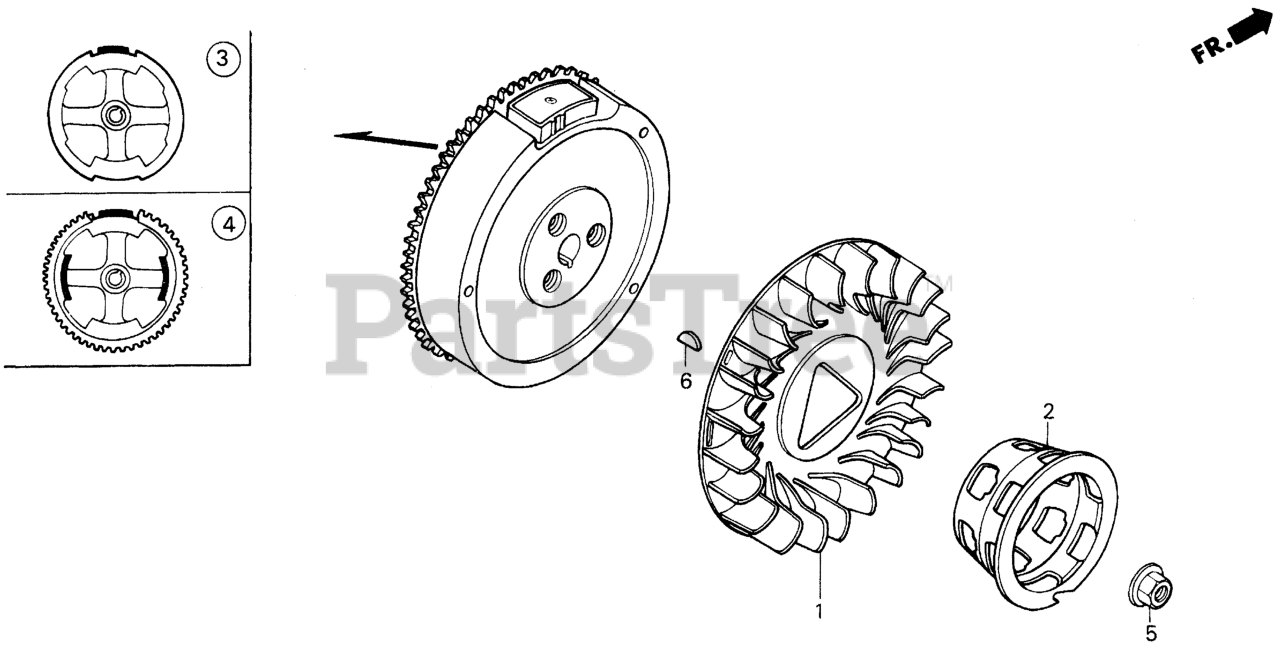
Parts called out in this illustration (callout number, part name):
1	FAN, COOLING
2	PULLEY, STARTER
3	FLYWHEEL
5	NUT, SPECIAL (16MM)
6	KEY, SPECIAL WOODRUFF (25X18)
